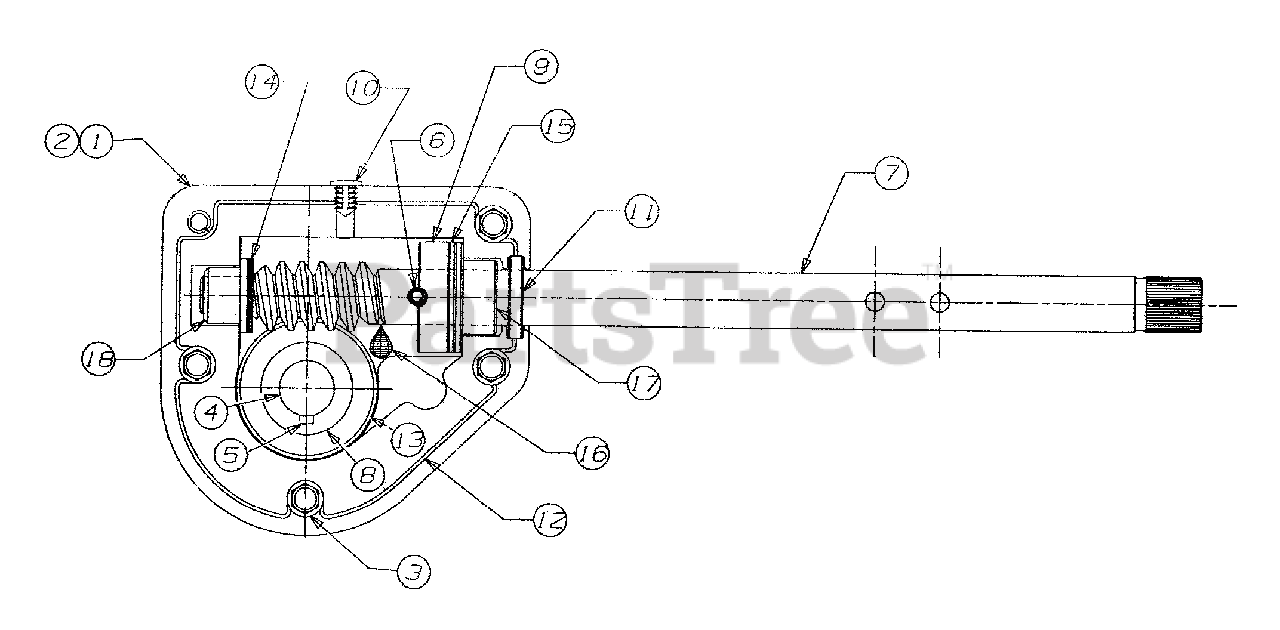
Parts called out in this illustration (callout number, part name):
1	Housing - R.H.
2	Housing - L.H.
3	Screw
4	Axle, Spiral 26"
5	Key, Hi-Pro
6	Pin, Spiral
7	Worm, Shaft
8	Gear, Worm
9	Collar, Thrust
11	Seal, Oil
12	Loctite 5699, Ultra
13	Washer
14	Washer
15	Washer
16	Grease
17	Bearing Flange
18	Bearing Flange
